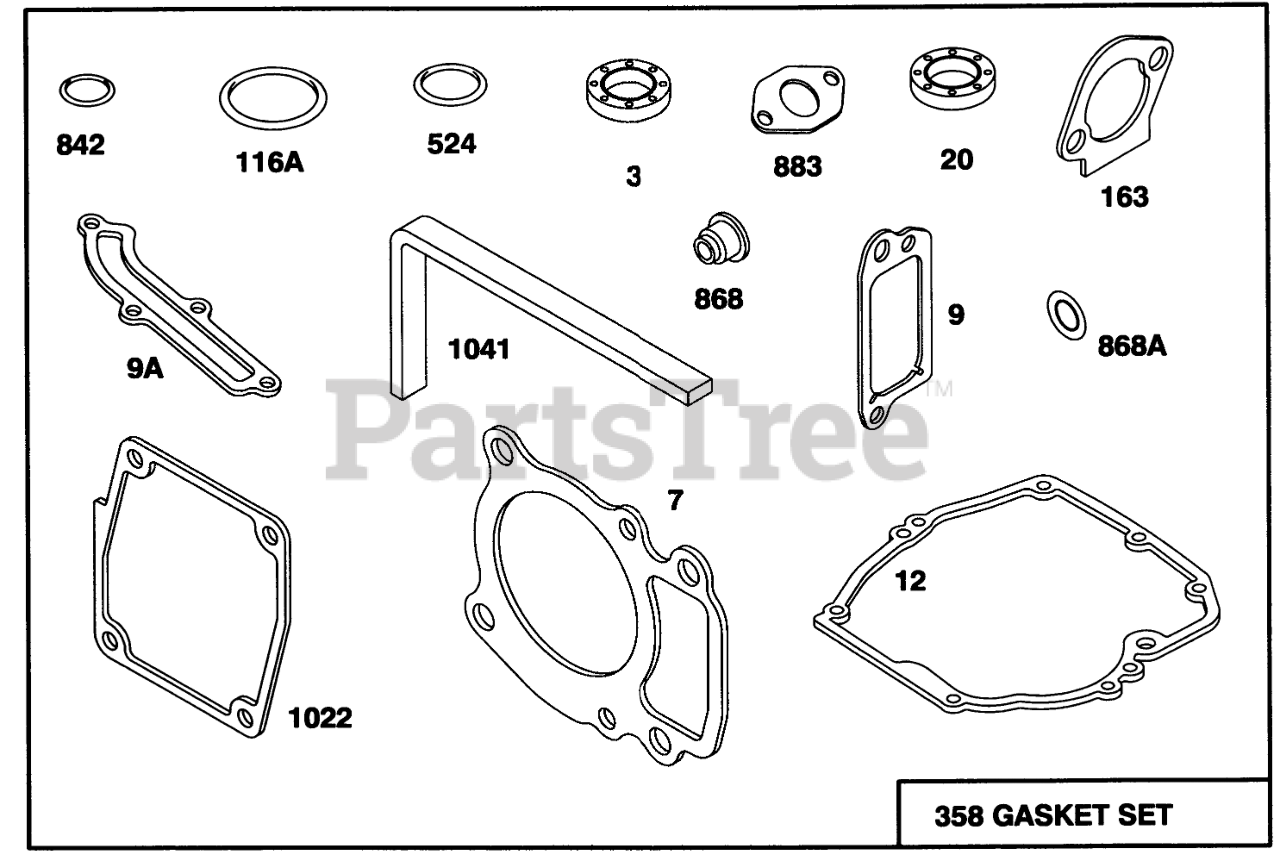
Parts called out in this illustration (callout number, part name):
3	SEAL - OIL
7	CYLINDER HEAD GASKET
9	Gasket-Breather
9A	GASKET-BREATHER
12	ENGINE BASE GASKET
20	SEAL-OIL
116A	O RING SEAL
163	AIR CLEANER GASKET
524	O-RING
842	O-RING
868	SealAssy-Valve
868A	Seal-Valve
883	EXHAUST GASKET
1022	ROCKER COVER GASKET
1041	SEAL - FOAM
